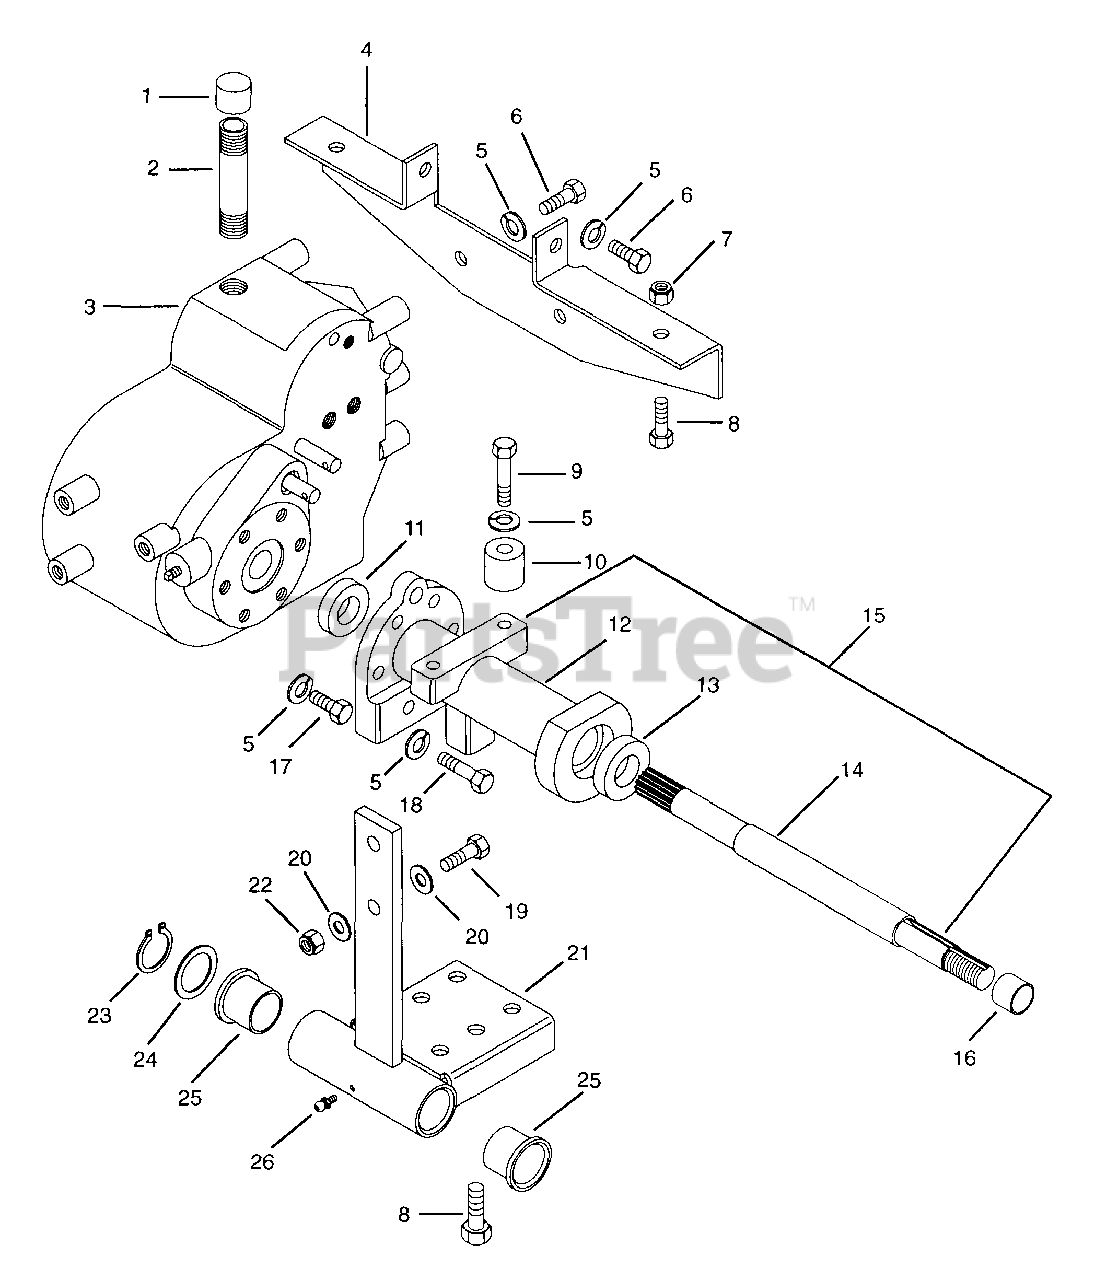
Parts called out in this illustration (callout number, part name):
1	Cap, Pipe
2	Nipple, Pipe .75 x 5.0
3	Transaxle
4	Plate, Transaxle
5	Washer-Lock .50 Reg.
6	Bolt-Hex .50-13 x 1.25 Grade 5
7	Nut-Locking-Nylon .625-11 Grade 2
8	Bolt-Hex .62-11 x 1.50
9	Bolt-Hex .50-13 x 2.75 Grade 5
10	Spacer, Frame
11	Ring, Alignment
12	Housing, Axle
13	Bearing, Ball 1.181 x 2.440 x .629
14	Axle
15	Assembly, Axle Housing
16	Spacer, Axle 1.38 x .800
17	Bolt-Hex .50-13 x 1.50 Grade 5
18	Bolt-Hex .50-13 x 2.25 Grade 5
19	Bolt-Hex .50-13 x 1.75
20	Washer-Flat-Steel .531 x 1.062 x .095
21	Weldment, Pivot Bracket
22	Nut-Locking-Nylon .50-13 Grade 5
23	Ring-Retaining-External 1.5 x 1.38
24	Washer-Thrust 1.502 x 2.18 x .063
25	Bushing-Flange 1.514 x 1.756 x 1.688 x 2.250
26	Fitting-Lube .25-28 x .256
